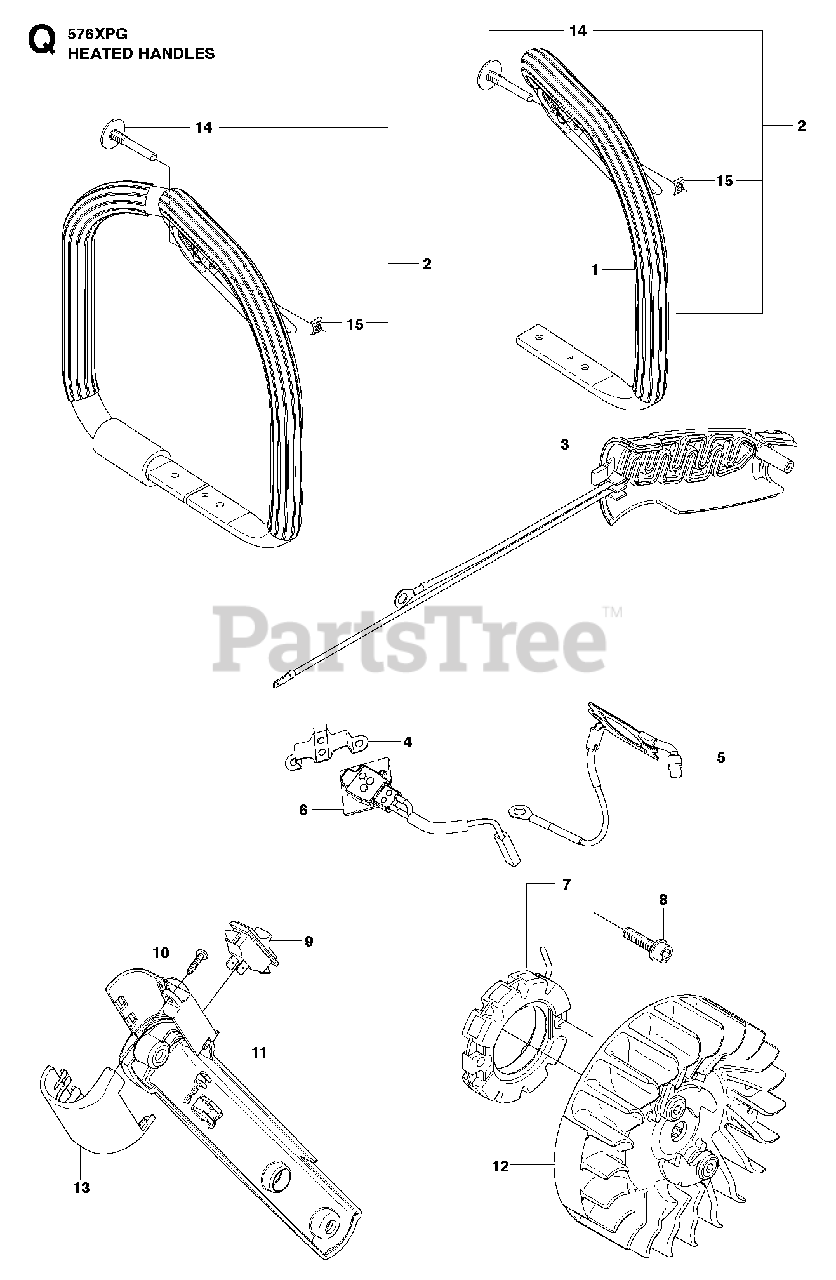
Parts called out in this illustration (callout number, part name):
1	HANDLE (G)
2	HANDLE (WAG)
5	HANDLE CIRCUIT
6	THERMOSTAT
14	SCREW
15	NUT
